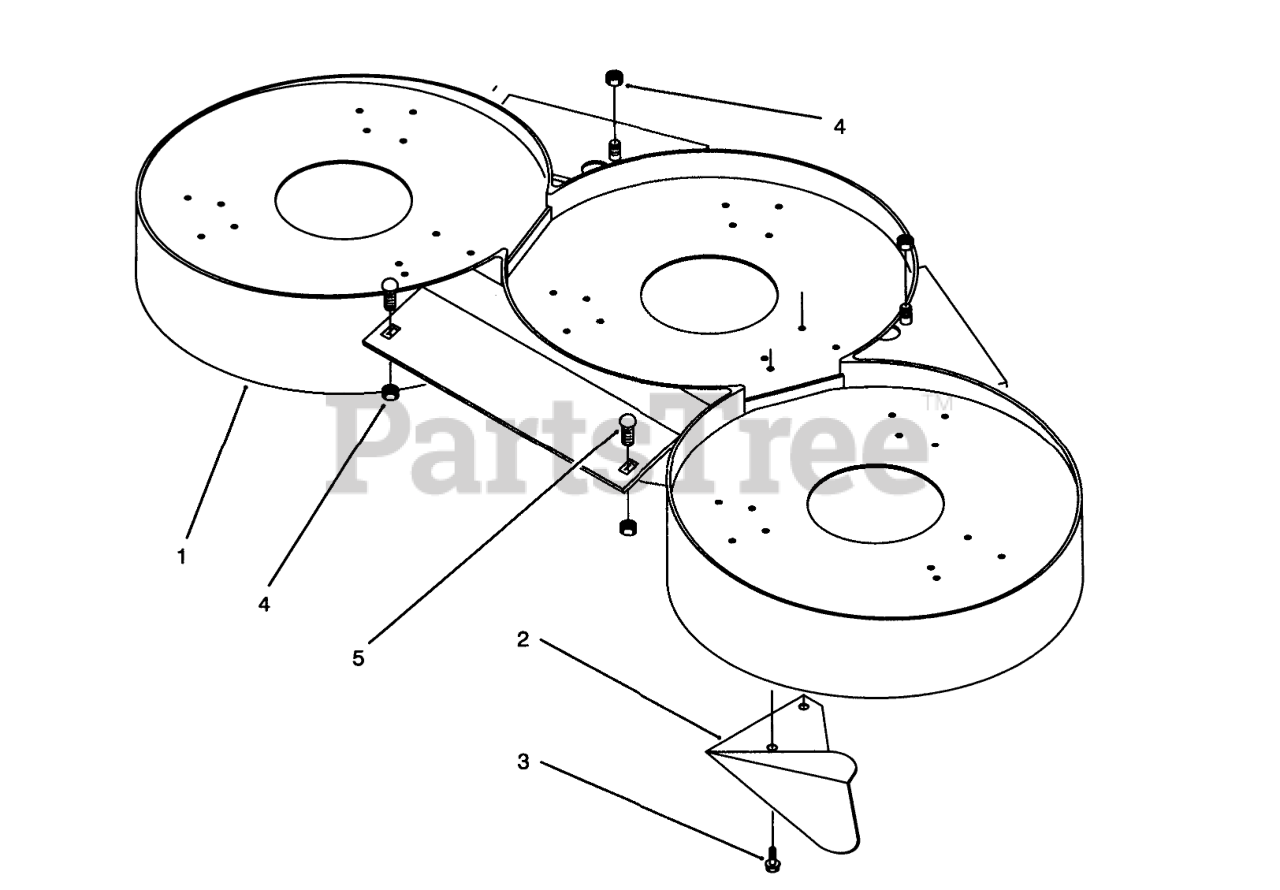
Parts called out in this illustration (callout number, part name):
1	Baffle
2	Kicker
3	SCREW-HWH
4	NUT-LOCK, NI
5	BOLT-CARR
